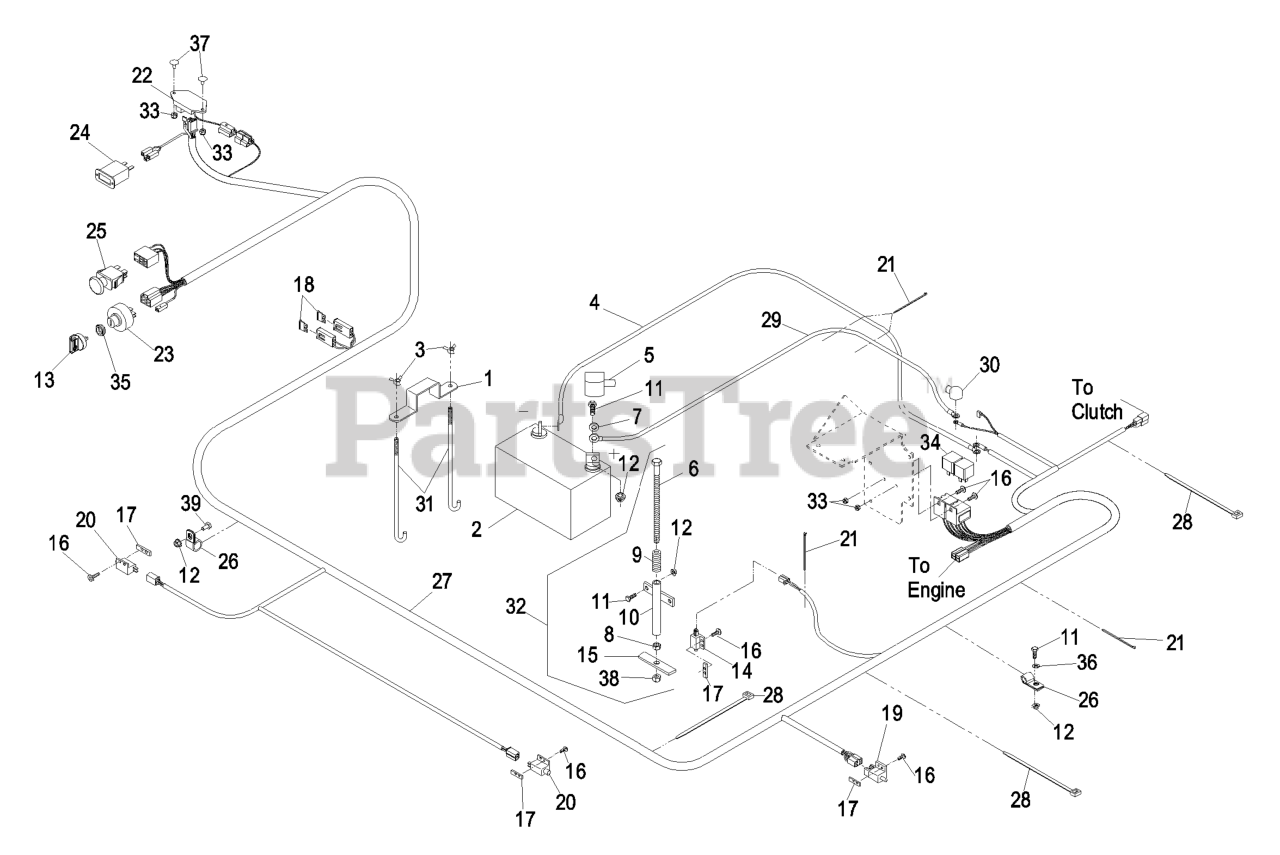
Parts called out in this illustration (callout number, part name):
1	STRAP-HOLDDOWN
3	WINGNUT
4	WIRE-GROUND
6	SCREW-HH
7	WASHER-FLAT
8	NUT-HEX
9	SPRING-SWITCH, SEAT
10	MOUNT-SPRING, SEAT
11	SCREW-HH
13	KEY-IGNITION
14	SWITCH-CLOSED, NORMALLY
15	PLATE-SWITCH, SEAT
16	SCREW-PPH
17	PLATE-TAPPED
18	FUSE-BLADE TYPE, 20 AMP
20	SWITCH-OPEN, NORMALLY
21	TIE-CABLE
22	MODULE-DELAY, SEAT
24	METER-HOUR
25	SWITCH-PTO
26	CLIP-LOOM
27	HARNESS,WIRE LAZER KC
28	TIE-PLASTIC
30	INSULATOR-SOLENOID
31	BOLT-HOLDDOWN
32	ASM,SEAT SWITCH ACTUATOR
33	NUT-LOCK, NI
35	NUT-SWITCH, IGNITION
36	WASHER-FLAT
37	BOLT-CARR
38	NUT-LOCK, NI
39	SCREW-HH
